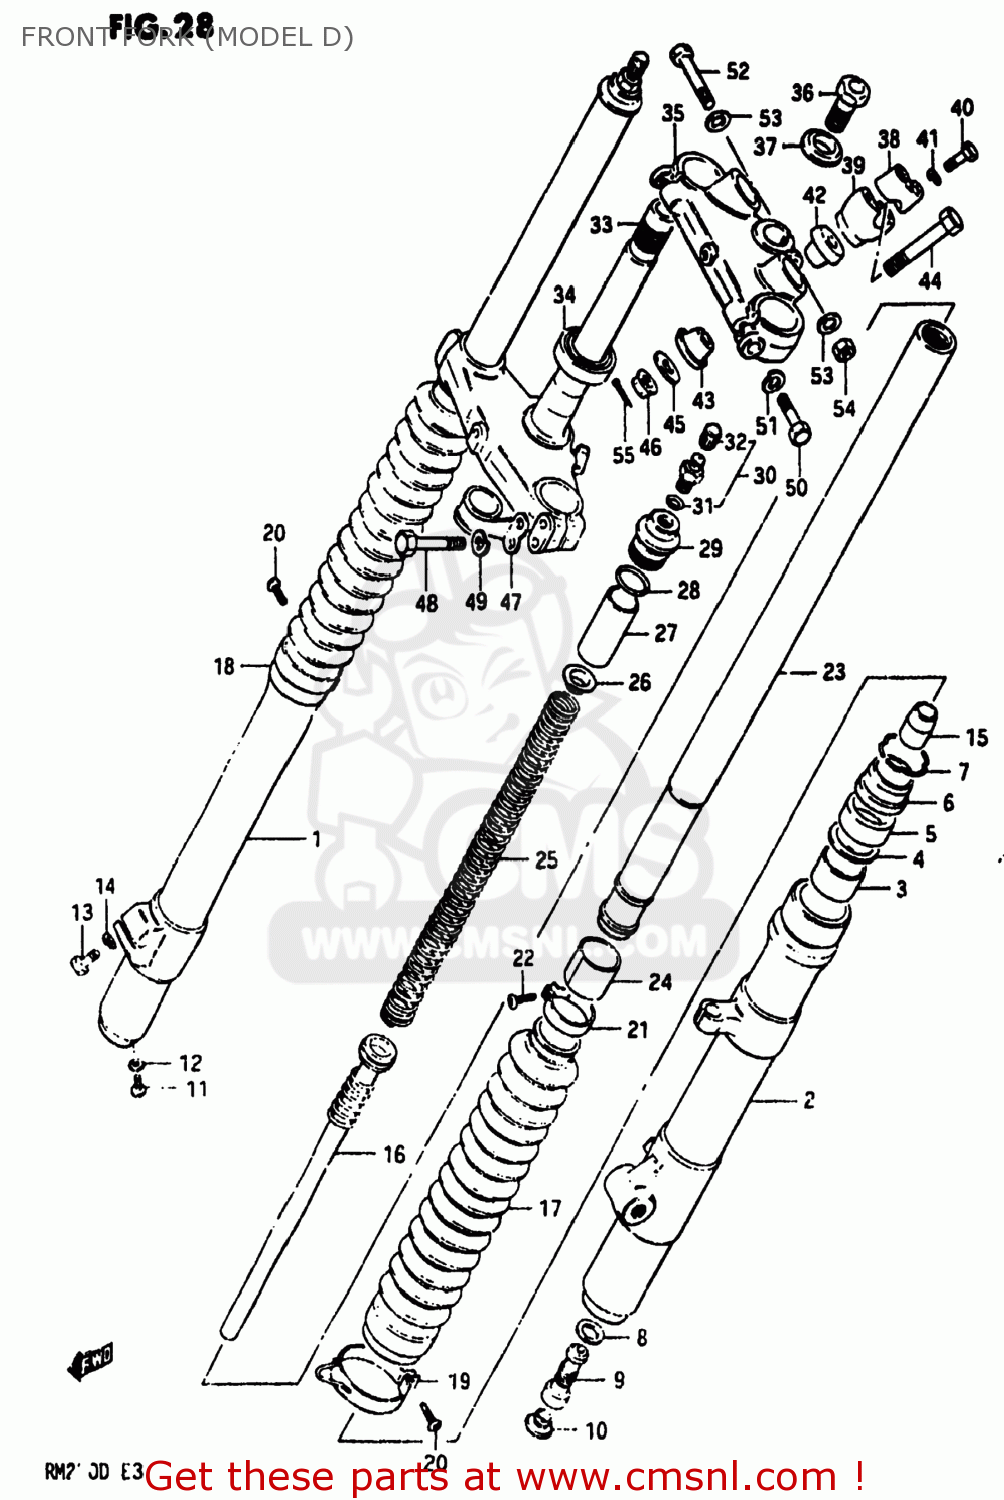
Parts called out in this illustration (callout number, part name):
1	TUBE,OUTER,RIGHT
2	TUBE,OUTER,LEFT
3	METAL,SLIDE
4	WASHER
5	SEAL,OIL
6	SEAL,DUST
7	RING,STOPPER
8	GASKET,FORK CYLINDER
9	VALVE,DF
10	CAP,FRONT FORK DF
11	SCREW 4X6
12	GASKET,DRAIN,PLUG (NAS)
13	BOLT (8X30)
14	WASHER,LOCK,8.
15	PIECE,FRONT FORK OIL LOCK
16	CYLINDER,FRONT FORK
17	BOOT,FRONT FORK COVER
18	BAND,BOOT,UPPER
19	BAND,FRONT FORK BOOT
20	SCREW
21	BAND,FRONT FORK BOOT
22	SCREW 4X10
23	TUBE,INNER
24	PISTON
25	SPRING,FRONT FORK
26	GUIDE,SPRING
27	SPACER,FRONT FORK SPRING
28	O RING
29	CAP,FORK INNER TUBE
30	VALVE,FRONT FORK AIR
31	O-RING
32	CAP,VALVE AIR
33	STEM,STEERING
34	BEARING
35	HEAD,STEERING STEM
36	BOLT
37	WASHER
38	HOLDER,HANDLE UPR
39	HOLDER,HANDLE LWR
40	BOLT
41	WASHER,LOCK,8.
42	DAMPER,UPR
43	DAMPER,LWR
44	BOLT,HANDLE HOLDER
45	WASHER,HANDLEBAR HOLDER
46	NUT
47	GUIDE,CABLE
48	BOLT 8X40
49	WASHER,LOCK,8.
50	BOLT
51	WASHER,LOCK,8.
52	BOLT 8X50
53	WASHER
54	NUT
55	PIN 20X20
